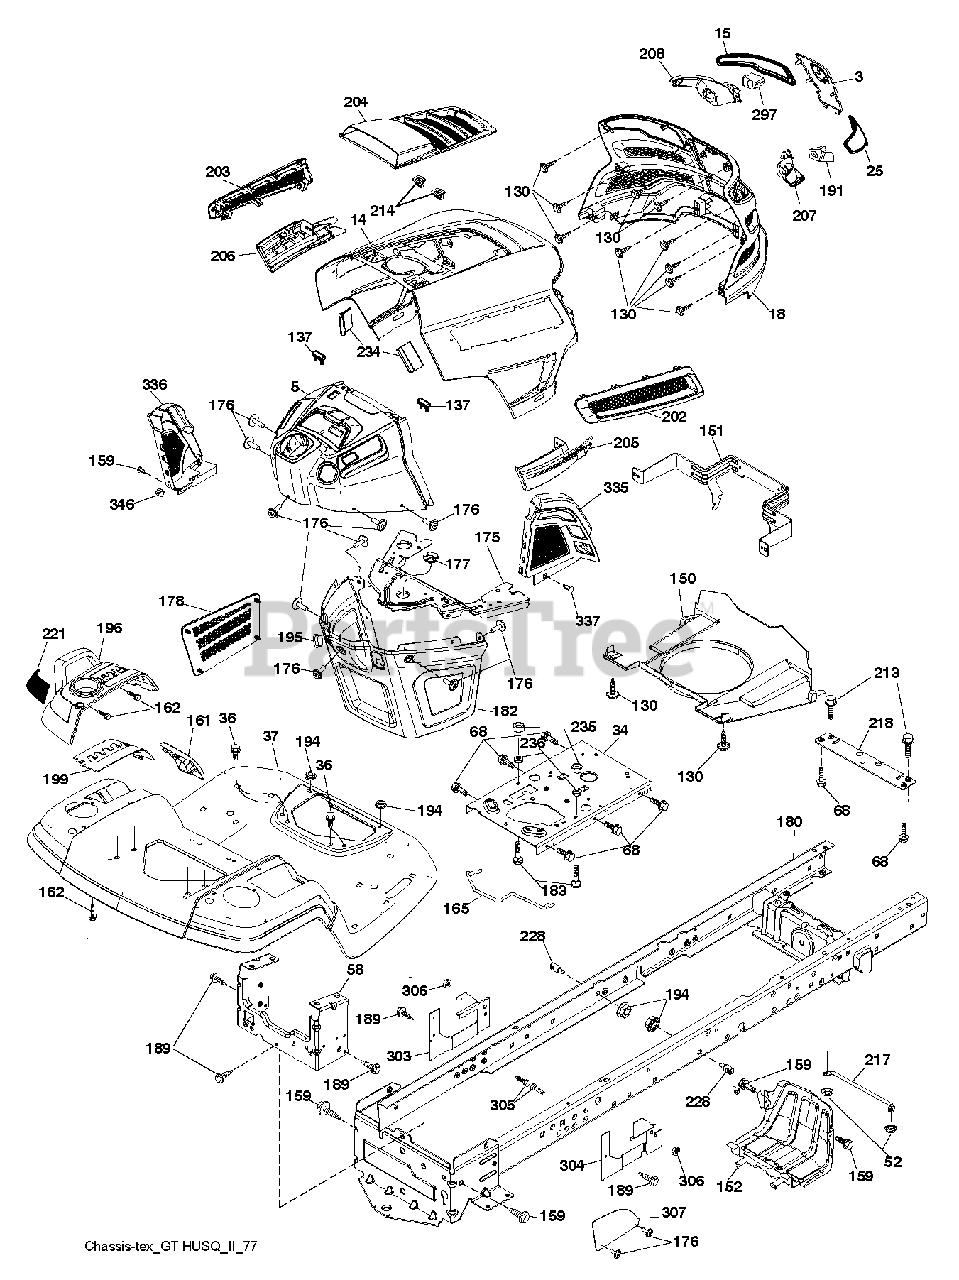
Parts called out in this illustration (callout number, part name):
3	APPLIQUE.SUBASM.GT.HUSQ.II
5	DASH.UPP.GT2.SM.PTO.MCHOKE
14	HOOD.ASM.HUSQVARNA.GT.TEX.ORAN
15	LENS.HEADLIGHT.LH.GTII.2011
18	GRILLE.SUBASM.GT.HUSQ.II
25	LENS.HEADLIGHT.RH.GTII.2011
34	PLATE.ENGINE.WELDED.CHASSIS
36	SCREW 5/16"
37	FENDER.PNT.TX.GT.CH/FW/DL.HUSQ
52	LOCKNUT
58	DRAWBAR.UPPER.2PC,LRG.FENDER
68	SCREW LT
130	SCREW.#10 X 0.750.BOS
137	BUMPER DASH
150	AIR.DUCT.GTV.BLACK
151	BRACKET.PIVOT.HOOD.GT.HUSQ.II
152	SHIELD.BROWNING.PNT.GT.V2
159	SCREW, 3/8-16X3/4
161	CONSOLE.WINDOW.FUEL.HUSQ.GT
162	SCREW.HI-LO.CONSOLE
165	SUPPORT.TANK.REAR.W/TEX
175	PLATE.CROSSMEMBER.HUSQ
176	SCREW.#10-24X5/8.RN.QU
177	BUSHING, STEERING
178	CARGO.ASM.NET.TXGT.W/C
180	CHASS.WLDMNT.TLT.12GA/2PC.20"
182	DASH.LOWER.COMMON.12V.ADAPTOR
183	BOLT.5/16-18X1-1/4 FULL THD
189	SCREW
191	INSERT.REFLECTIVE.RH.HUSQ.GTII
194	NUT LOCK HEX FLANGE 5/16-18
195	PLUG.HOLE.DASH.LOWER.12V.BLK
196	SUBASM.CONSOLE.HUSQ.GT.DECKLFT
199	PLATE.DECK.LIFT.HUSQVARNA.GT
202	VENT.SIDE.RH.GT.HUSQ.II.
203	VENT.SIDE.LH.GT.HUSQ.II.498
204	VENT.TOP.HUSQ.GT2
205	SIDE.TRIM.RH.GT.HUSQ.II
206	SIDE.TRIM.LH.GT.HUSQ.II.GRAY
207	BEZEL LIGHT.RH.GT.II.MYLAR
208	BEZEL LIGHT.LH.GT.II.MYLAR
213	BOLT
214	CLIP.RETAINER.TINNER.
217	ROD.PIVOT.HOOD
218	X-PIECE.HOOD.STOP.NON/
221	REFLECTOR.LH.TEX GT HU
228	STUD.FASTNER.W/ANTI-ROTATE
234	BUMPER.HOOD.TEX.HUSQVARNA
235	SPACER FENDER
236	NUT.CENTERLOCK.5/16-
297	INSERT.REFLECTIVE.LH.HUSQ.GTII
303	SHIELD CHASSIS LEFT
304	SHIELD CHASSIS RIGHT
306	NUT LOCK FLG 3/8-16 UNC
307	SHIELD UPPER PEDAL
335	COVER.RH.CLOSE.OUT.BLACK
336	COVER-LH.LOWER.DASH.GT2.BLACK
337	CLIP.XMAS.TREE.ITW.2622-00
346	CLIP,INSULATOR
